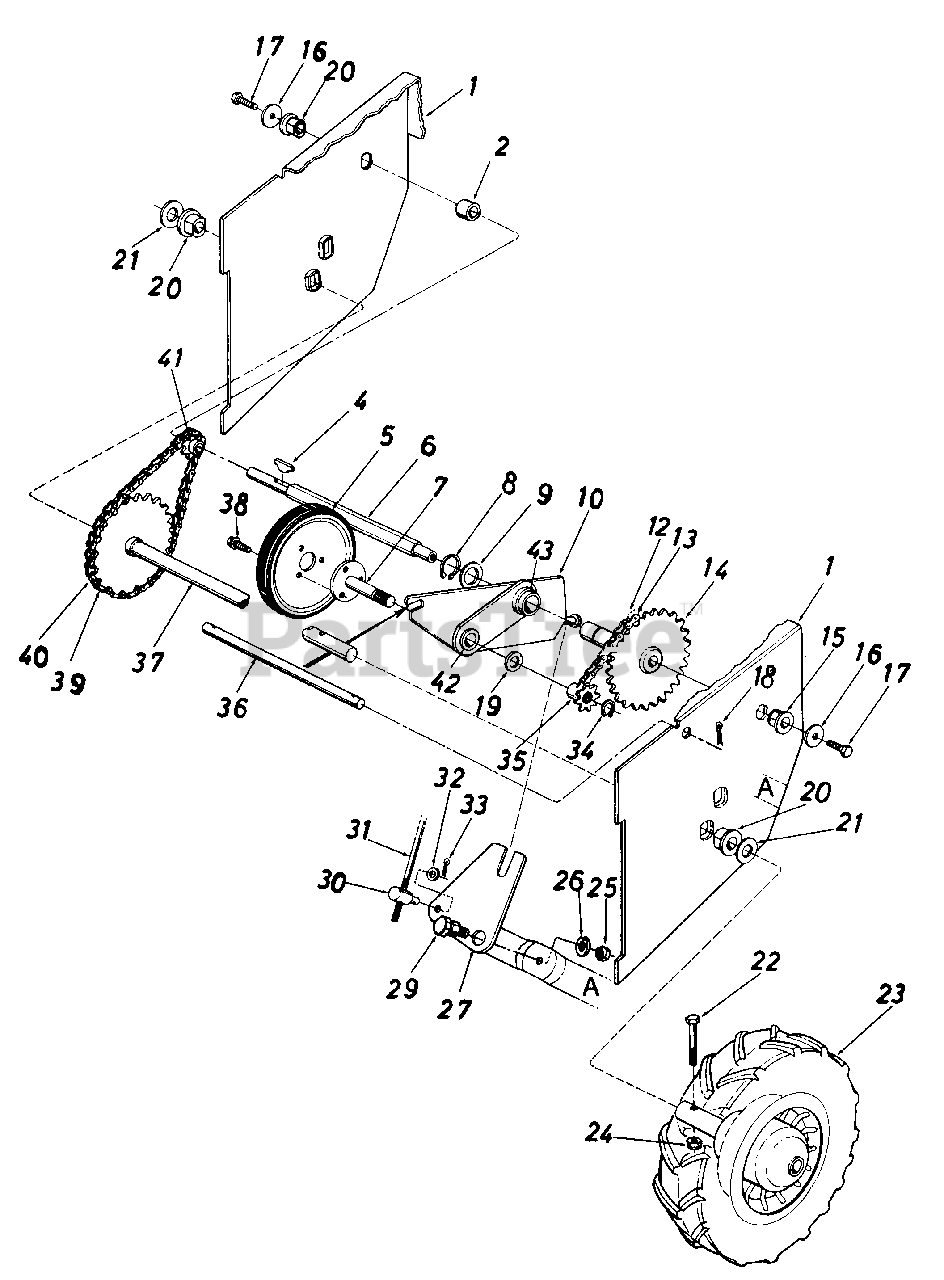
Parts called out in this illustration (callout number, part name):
1	Frame Ass'y.
2	Spacer .50" I.D. x .75" O.D. x .78" Lg.
4	#4 Hi-Pro Key 3/32 x 5/8" Dia.
5	Friction Wheel Ass'y.
6	Hex Shaft
7	Friction Wheel Mounting Plate Ass'y.
8	Snap Ring 1.00" Dia. Shaft
9	Fl-Wash. 1.03" x 1.62" O.D. x .03
10	Sliding Bracket Ass'y.
12	#41 Chain 1/2" Pitch x 35 Links
13	Master Link for #41 Chain
14	32 Teeth Sprocket Ass'y.
15	Hex Flange Brg. .630" I.D.
16	Fl-Wash. .62" I.D. x 1.00" 0.0. x .06
17	Hex Lock Bolt 5/16-18 x .62" Lg.
18	Cotter Pin 3/32" Dia. x .75" Lg.
19	Fl-Wash. .62" I.D. x 1.00" O.D. x .06
20	Flange Brg. w/Flats .755" I.D.
21	Fl-Wash. .34" I.D. x 1.12" O.D. x .125
22	Hex Bolt 5/16-24 x 1.75" Lg.
23	Wheel Ass'y. Comp. - L.H. 12.5 x 3.5
24	Hex Ins. Jam L-Nut 5/16-24 Thd.
25	Hex Jam Nut 3/8-16 Thd.
26	L-Wash. 3/8" I.D.
27	Shifting Linkage Bracket
29	Shld. Bolt .625" Dia. x .170" Lg.
30	Adjustment Ferrule
31	Shifting Rod 5/16" Dia. x 32.50" Lg.
32	Fl-Wash. .34" I.D. x .64" O.D. x .06
33	Cotter Pin 3/32" Dia. x .75" Lg.
34	Snap Ring .562" Dia. Shaft
35	Sprocket 7 Teeth x .50" Pitch
36	Shaft .50" Dia. x 9.50" Lg.
37	32 Teeth Wheel Axle Ass'y.
38	Hex Wash. Hd. Self-Tap Scr. 5/16-24 x .50" Lg.
39	#420 Chain 1/2" Pitch x 39 Links
40	Master Link for #420 Chain
41	8 Teeth Center Sprocket
42	Plastic Bearing
43	Bronze Bearing
